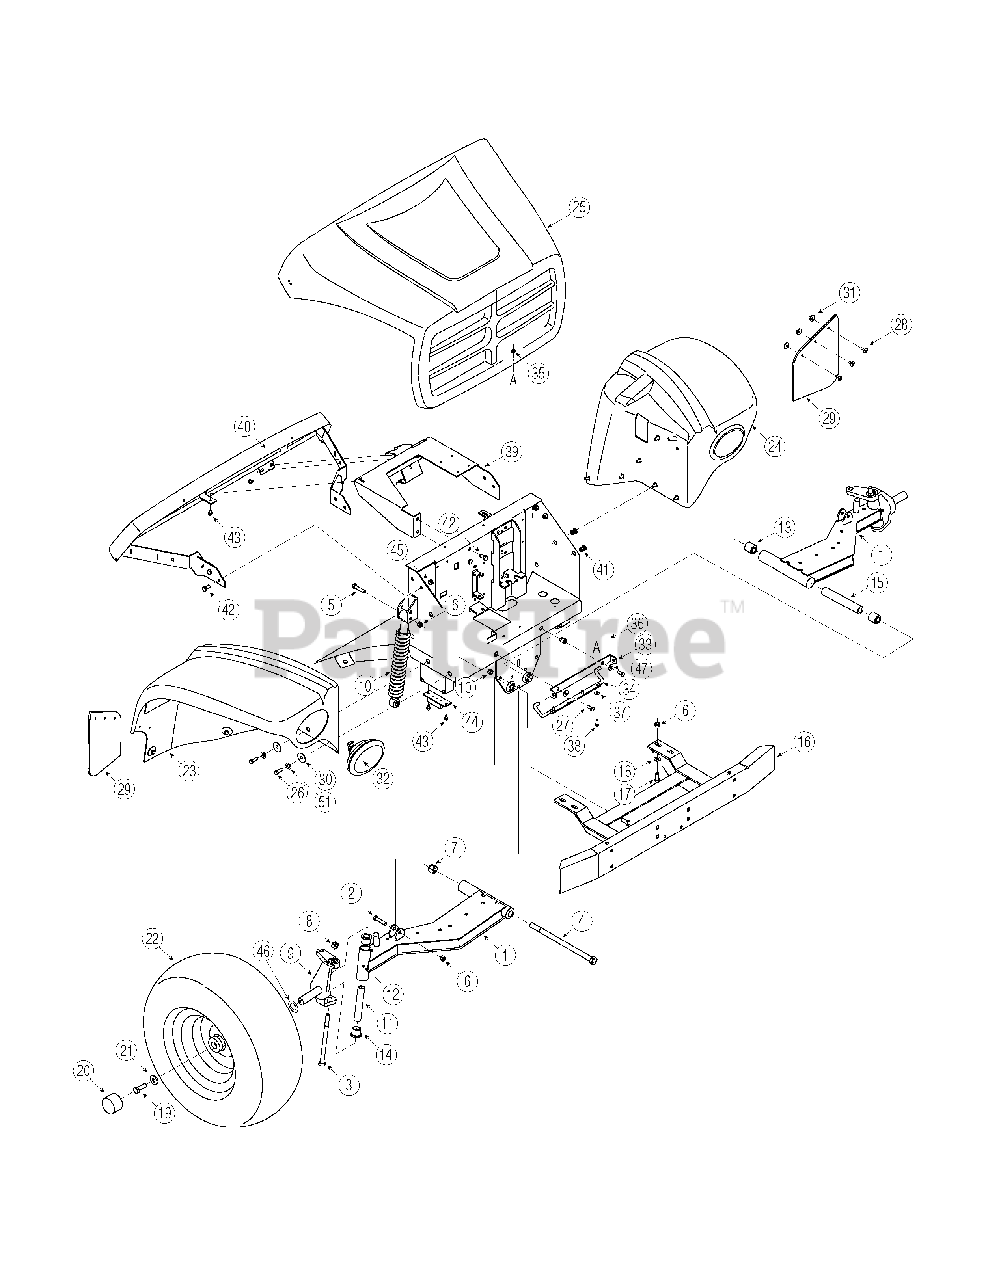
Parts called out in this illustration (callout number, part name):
1	Axle Assembly, Right-front (Incl. Ref 12-15)
2	Hex Screw, 3/8-16 x 1.75
3	Hex Screw, 1/2-13 x 7.0, Gr5
4	Hex Screw, 5/8-11 x 11.13, Gr5
5	Hex Screw, 3/8-16 x 2.25
6	Nut, Hex Lock, Nylon, 3/8-16, Gr5
7	Nut, Hex Lock, Nylon, 5/8-11, Gr5
8	Nut, Hex Lock, 1/2-13
10	Shock Absorber, 2.9 Stroke
11	Tube, .875 x .50 x 4.75
12	Grease Fitting
13	Bearing, .63 ID x 1.19 OD
14	Bushing, Steering
15	Spacer, .645 ID x 1.063 OD
18	Flat Washer,.406 x.875 x.059
19	Hex Screw, 1/2-13 x 1.25, Gr5
21	Flat Washer,.531 x 1.25 x.181
22	Wheel Ass’y, 22 x 11 x 10, RH, All Terr.
23	Panel, Right Fender, Yellow
24	Panel, Left Fender, Yellow
25	Panel, Hood, Yellow
26	Hex Screw 5/16-18 x 1.00 Gr 5
27	Hex Screw, 5/16-18 x.75
28	Pop Rivet
30	Washer, Bell .39 x 1.38 x .062
31	Flat Washer, .194 x .62 x .063
32	Head lamp Assembly
35	Nut, Hex Lock, 1/4-20
36	Cotter Pin, Internal, 1.42
37	Washer, Flat,.271 x.63 x.065
38	Hex Screw, 1/4-20 x.75
41	Insert Nut, 5/16-18
42	Hex Screw, 3/8-16 x.75
43	Screw, Self-tapping, 1/4-20 x.5
44	Suspension Bumper
45	Flange Lock Nut, 3/8-16
46	Washer, Flat, 030 x .625 x .090
47	Flat Washer .344 x .688 x .065
